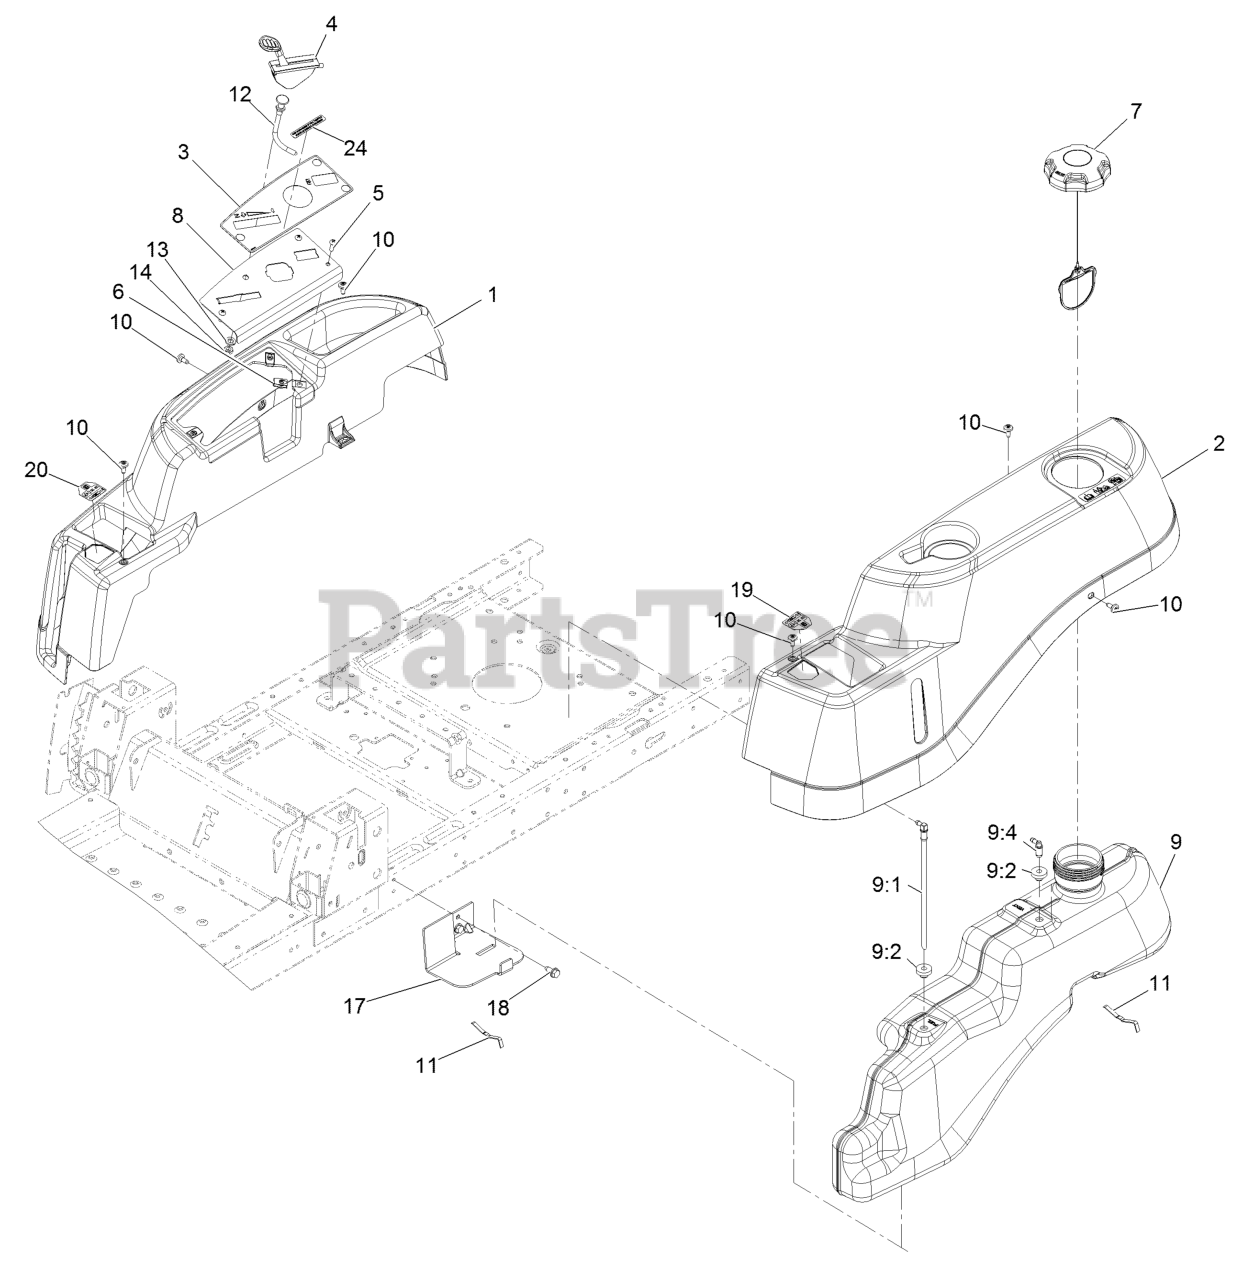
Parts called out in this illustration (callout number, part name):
3	DECAL-PANEL, CONTROL
4	CABLE-THROTTLE
5	SCREW-PRH
6	Nut-Retainer-Panel 1/4-20
8	PLATE-CONTROL
9	FUEL TANK ASM
9:1	CONNECTOR-ELBOW, 90 DEG
9:2	BUSHING
9:4	FITTING-PLASTIC
10	SCREW-SHOULDER
11	SPRING
12	CABLE-CHOKE
13	WASHER-LOCK
14	NUT-HJ
17	SUPPORT-TANK, FRONT
18	Screw-HWH 5/16-18 X 3/4 Tf
19	DECAL-LEVER, CONTROL (LH)
20	DECAL-LEVER, CONTROL (RH)
24	DECAL-SHUTDOWN
